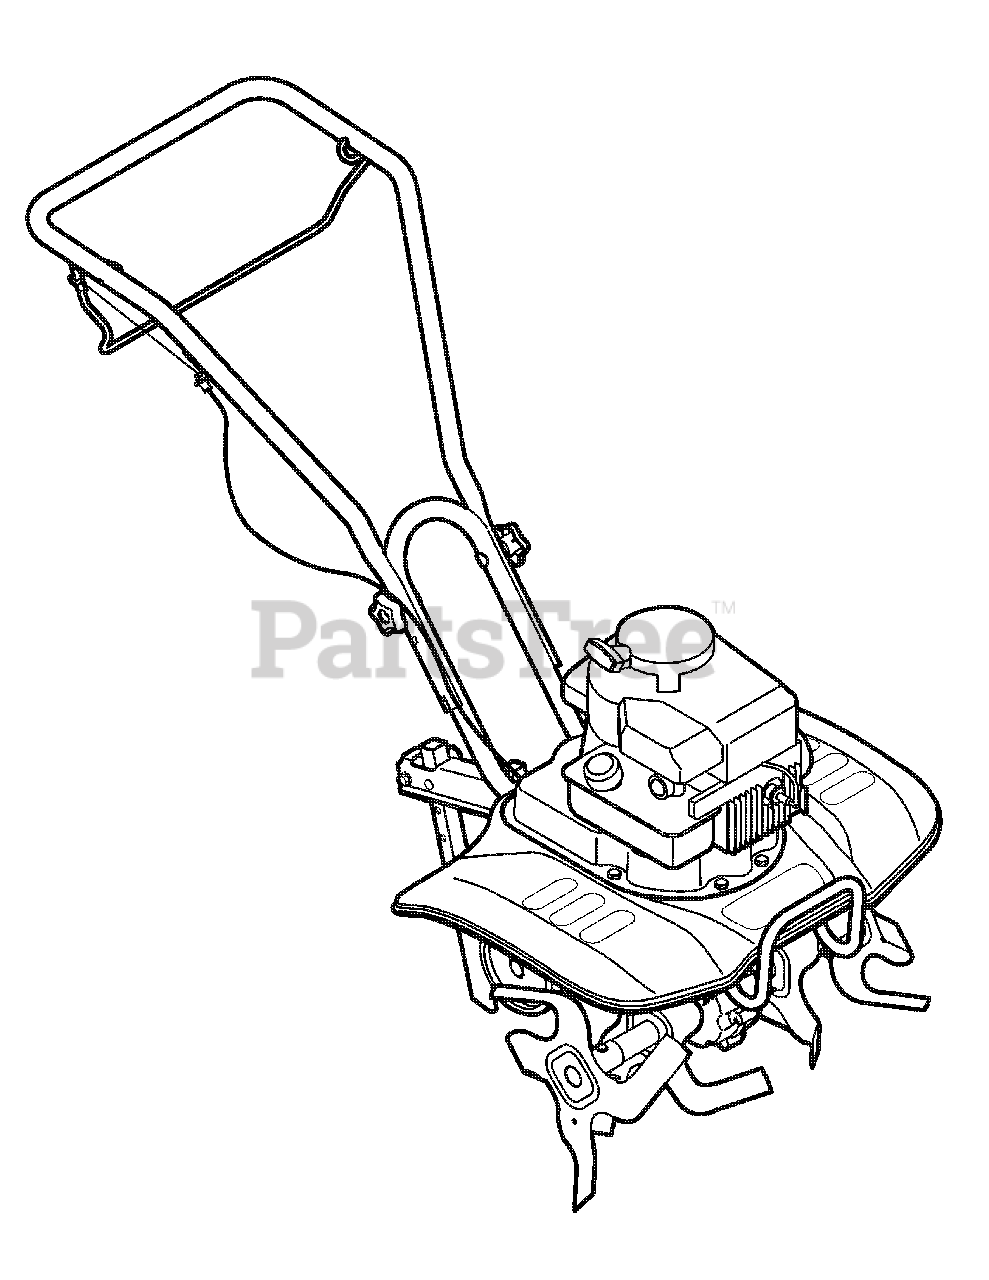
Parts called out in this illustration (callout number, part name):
NA	Pre Filter
NA	Drive Belt
NA	Clutch Cable
NA	Rim
NA	Tire
NA	Foam Grip
